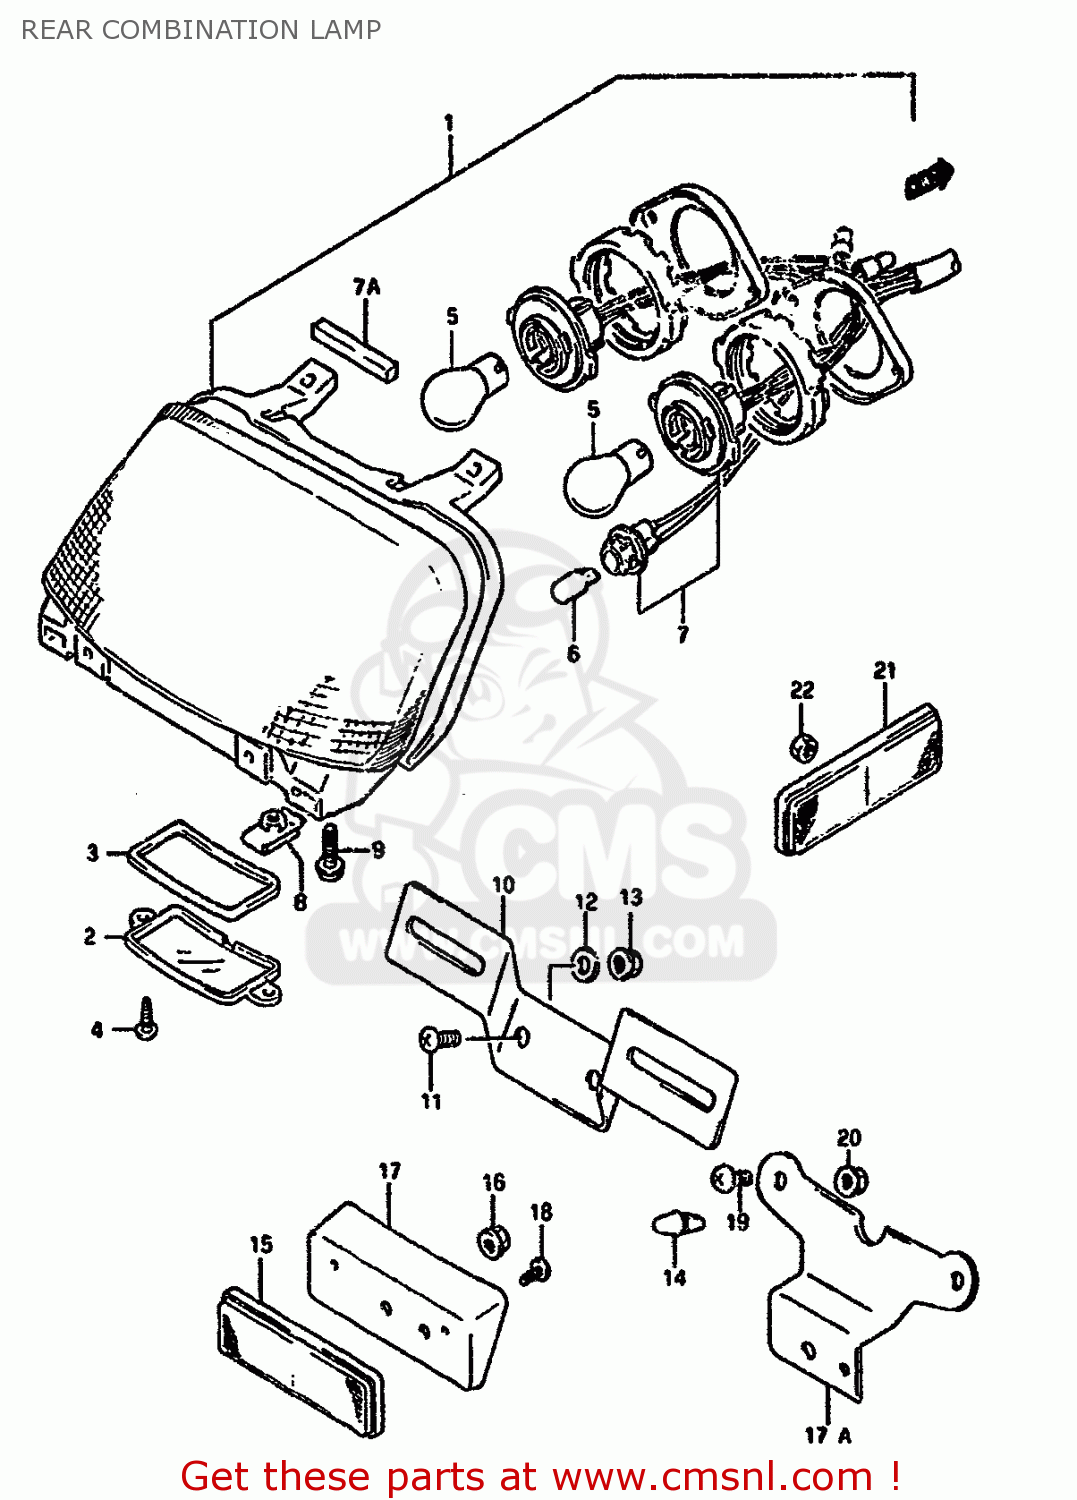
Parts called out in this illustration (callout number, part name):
1	LAMP ASSY,RR COMBINATION
2	LENS,LICENSE
3	GASKET (NAS)
4	SCREW
5	BULB(12V21/5W)
6	BULB(12V5W)
7	CORD ASSEMBLY
7A	CUSHION,HANDLE COVER
8	NUT,HEADLAMP HOUSING,UPPER
9	SCREW
10	PLATE,RR LICENSE
11	SCREW
12	WASHER (6.3X14X1.6)
13	NUT
14	CUSHION
15	REFLECTOR ASSY,RR
16	NUT
17	SPACER,RR RR
17A	BRACKET,RR RR
18	SCREW
19	SCREW 6X12
20	NUT
21	REFLEX REFLECTOR,FR SIDE
22	NUT
